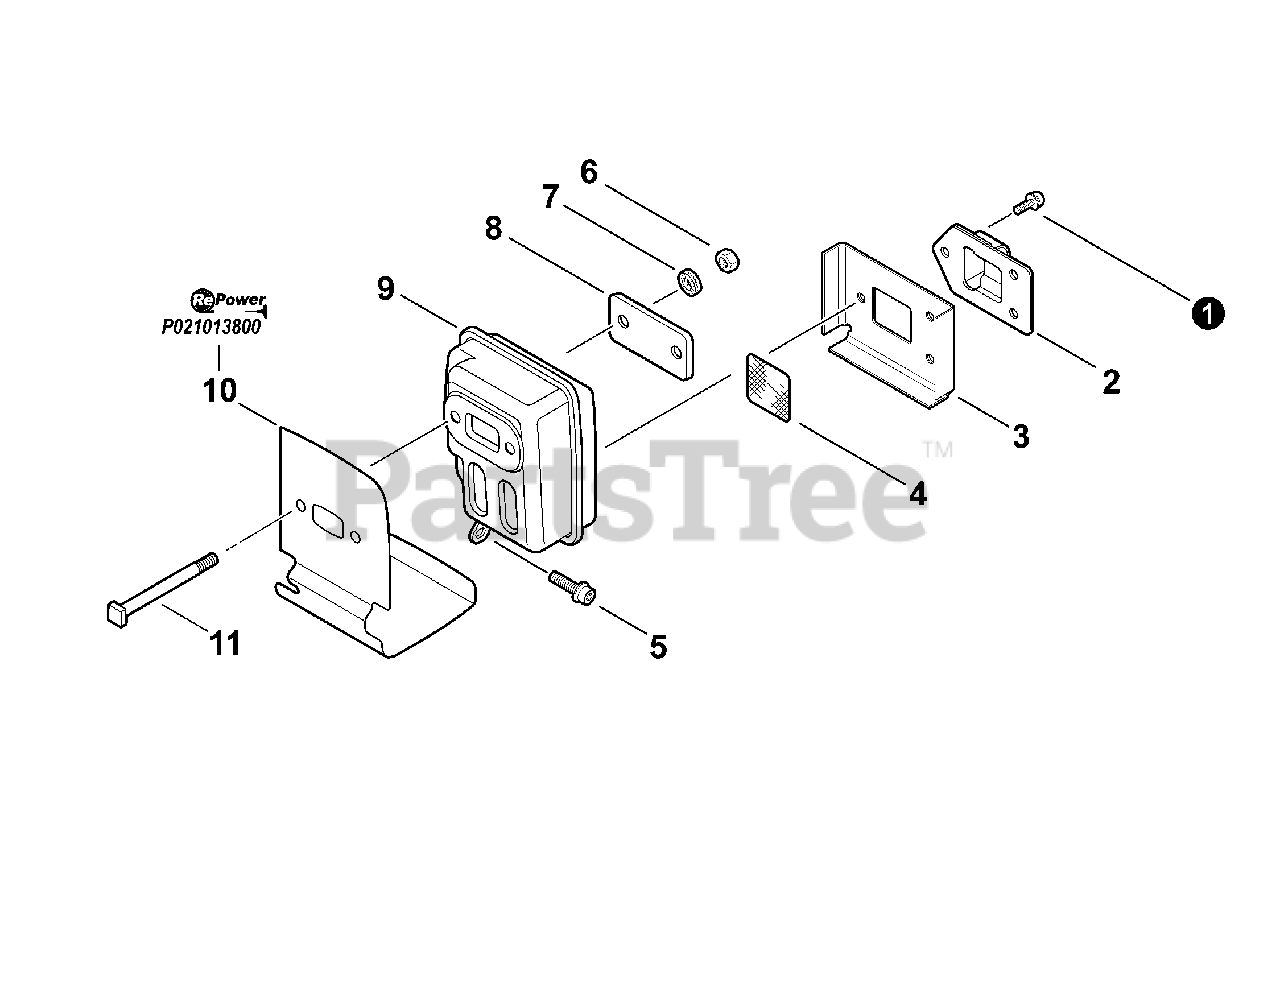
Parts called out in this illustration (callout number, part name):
1	SCREW - 4×10
2	GUIDE, EXHAUST
3	GASKET, EXHAUST
4	SCREEN, SPARK ARRESTER
5	SCREW - 5×16
7	LOCKWASHER
9	MUFFLER
10	SHIELD, EXHAUST
11	BOLT - 5
